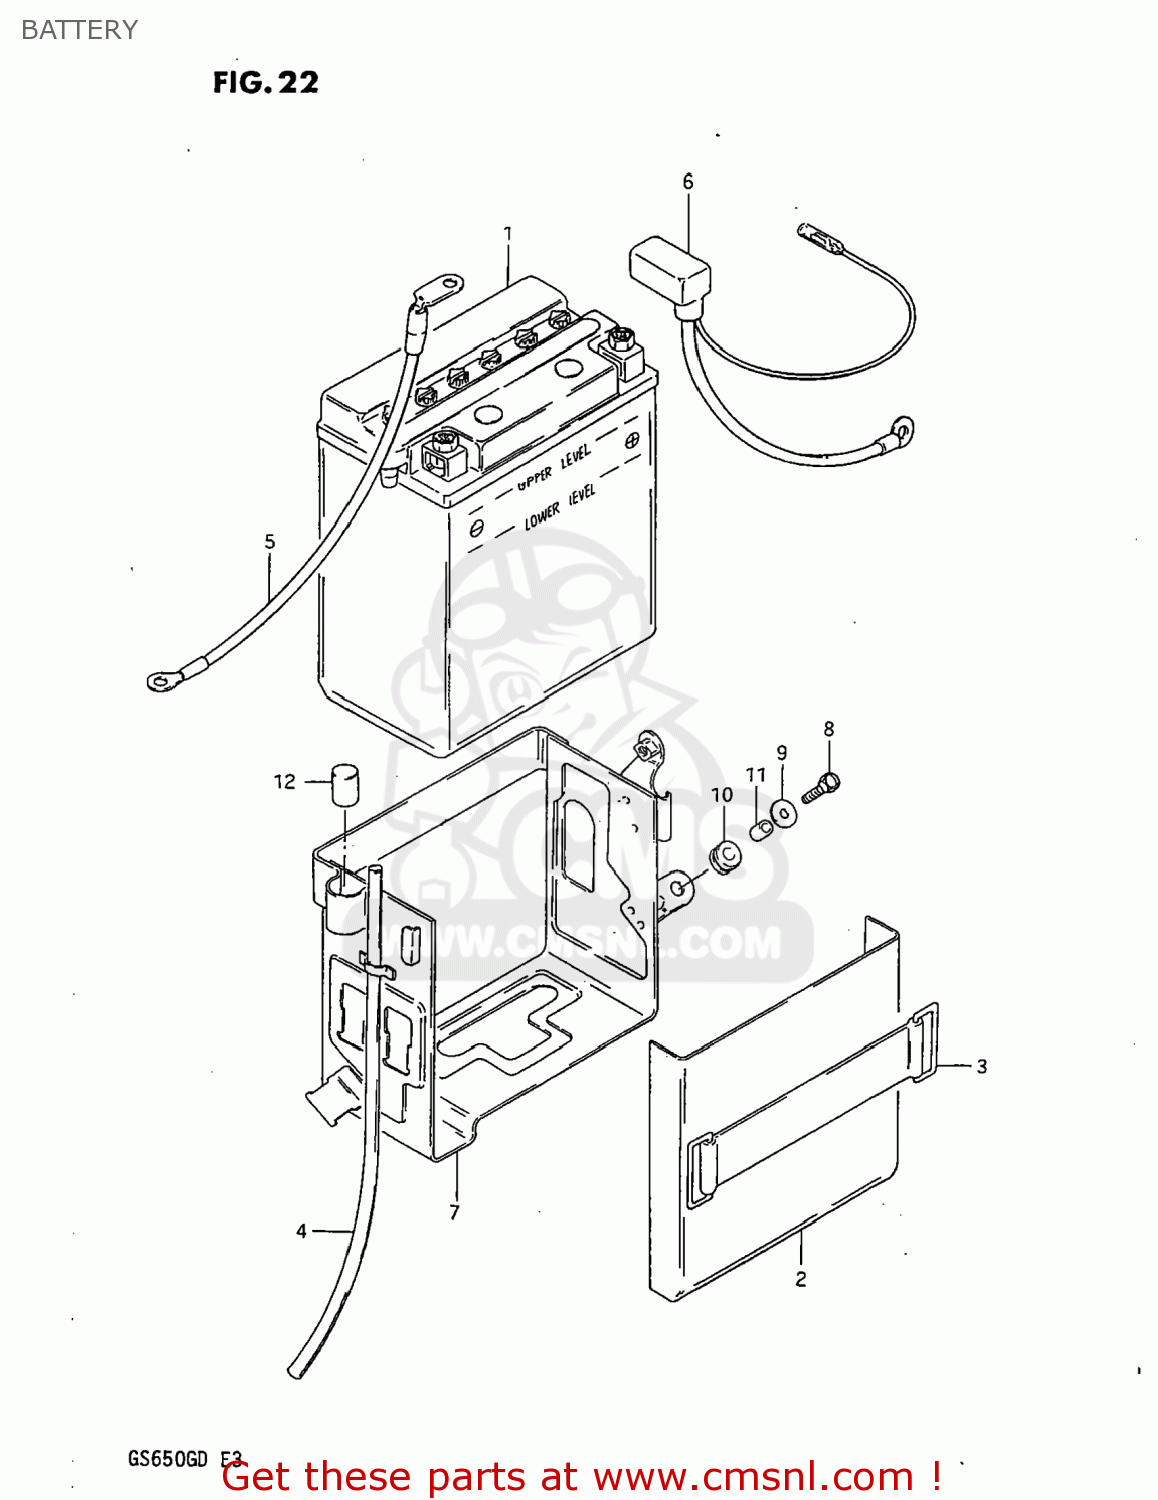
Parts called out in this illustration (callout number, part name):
1	BATTERY ASSY (12V)
2	COVER,BATTERY
3	BAND
4	HOSE,BATTERY EXHAUST
5	CORD,BATTERY MINUS
6	CORD,BATTERY PLUS
7	HOLDER,BATTERY
8	BOLT
9	WASHER
10	CUSHION
11	SPACER(6.1X9X7.5)
12	CUSHION
